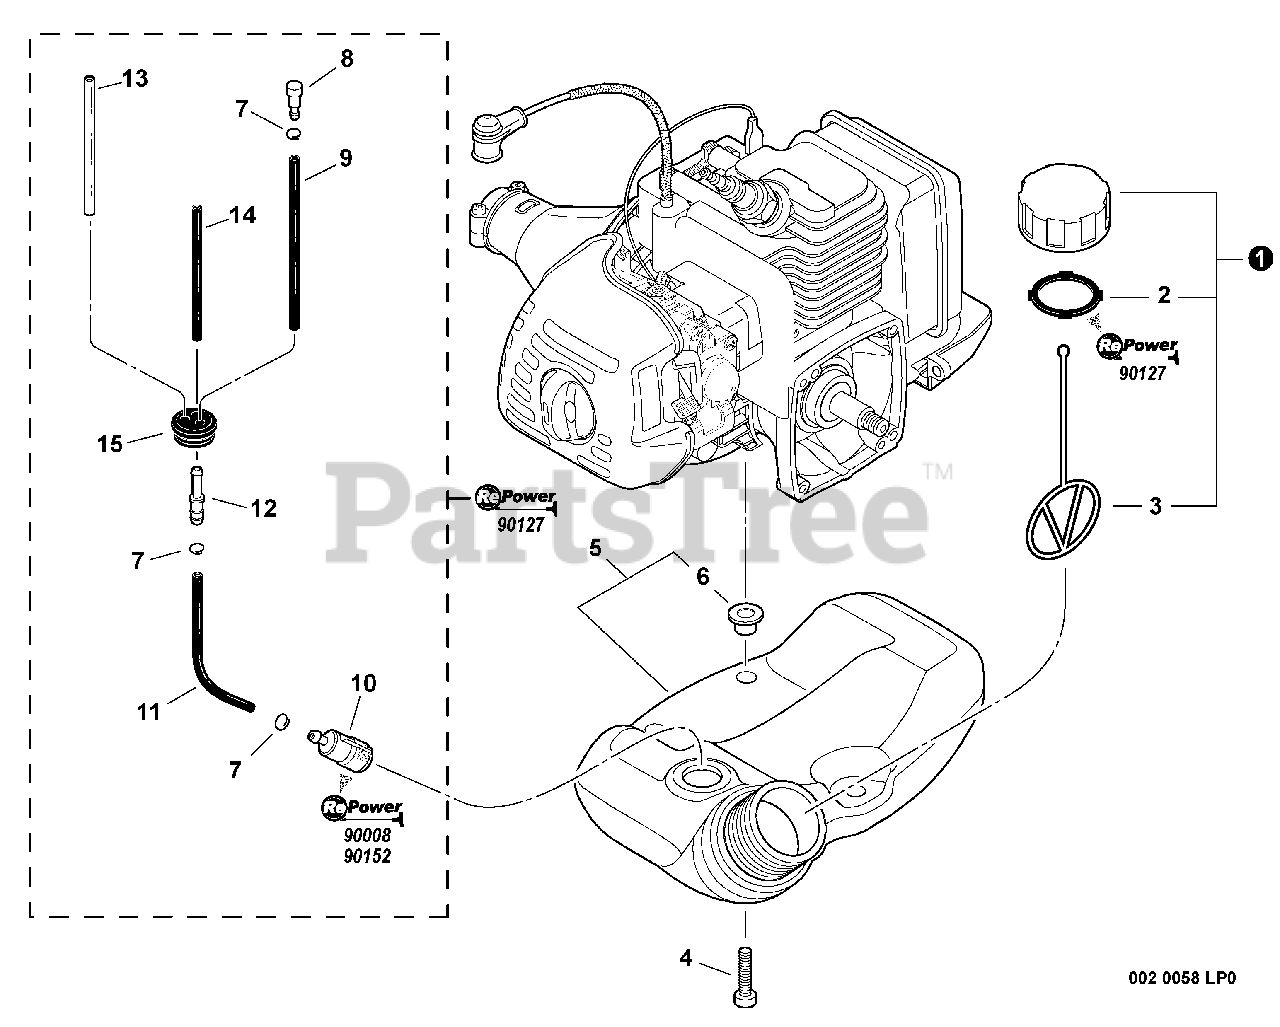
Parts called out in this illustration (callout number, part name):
1	CAP ASSY, FUEL
2	GASKET, FUEL CAP
3	CONNECTOR, CAP L= 123
4	BOLT, TORX 5×20
5	TANK ASSY, FUEL
6	COLLAR 5
7	CLIP Ø6
8	VENT ASSY
9	PIPE, FUEL 3×5×90 BLACK
10	FILTER, FUEL
11	PIPE, FUEL 3×5×130 BLACK
12	CONNECTOR, PIPE Ø5ר3.5
13	PIPE, FUEL 3×6×80 CLEAR
14	PIPE, FUEL 3×5×74 BLACK
15	GROMMET, FUEL Ø5
16	FUEL SYSTEM KIT
17	TUNE-UP KIT - REPOWER
18	FILTER KIT - REPOWER
19	BULK PIPE - 3×5 MM BLACK (4 PIECES×2 M)
20	BULK PIPE - 3×6 MM CLEAR (4 PIECES×2 M)
